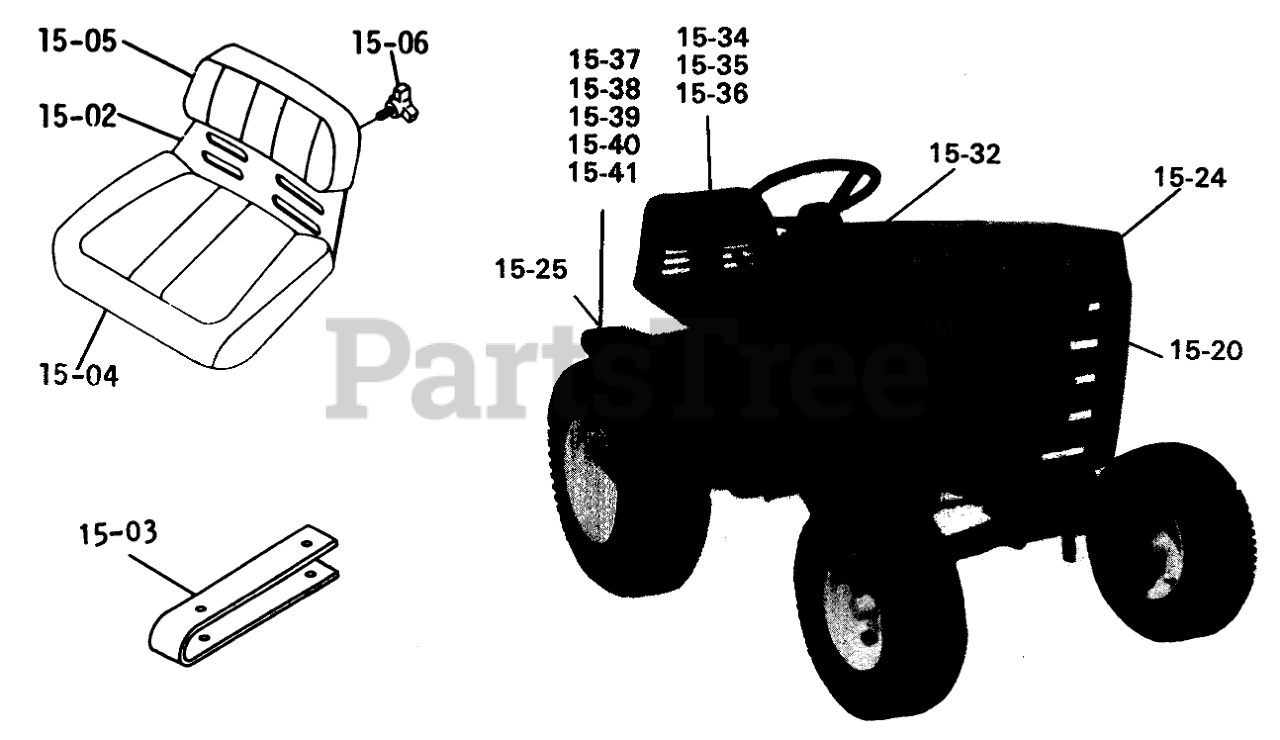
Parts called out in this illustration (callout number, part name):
15-02	Seat Base
15-03	Spring
15-04	Seat Cushion
15-05	Back Cushion
15-06	Knob 8 HP
15-20	Decal
15-25	DECAL-WHEEL HORSE
15-32	DECAL C-120 8-SPEED
15-34	Washer
15-35	Decal-Read Manual
15-36	DECAL-HAND LIFT
15-37	DECAL-4 SPD SHIFT
15-38	Decal-Park Brake
15-39	Decal
15-40	Decal-Tach-a-matic
15-41	DecaI-Hi-Lo
